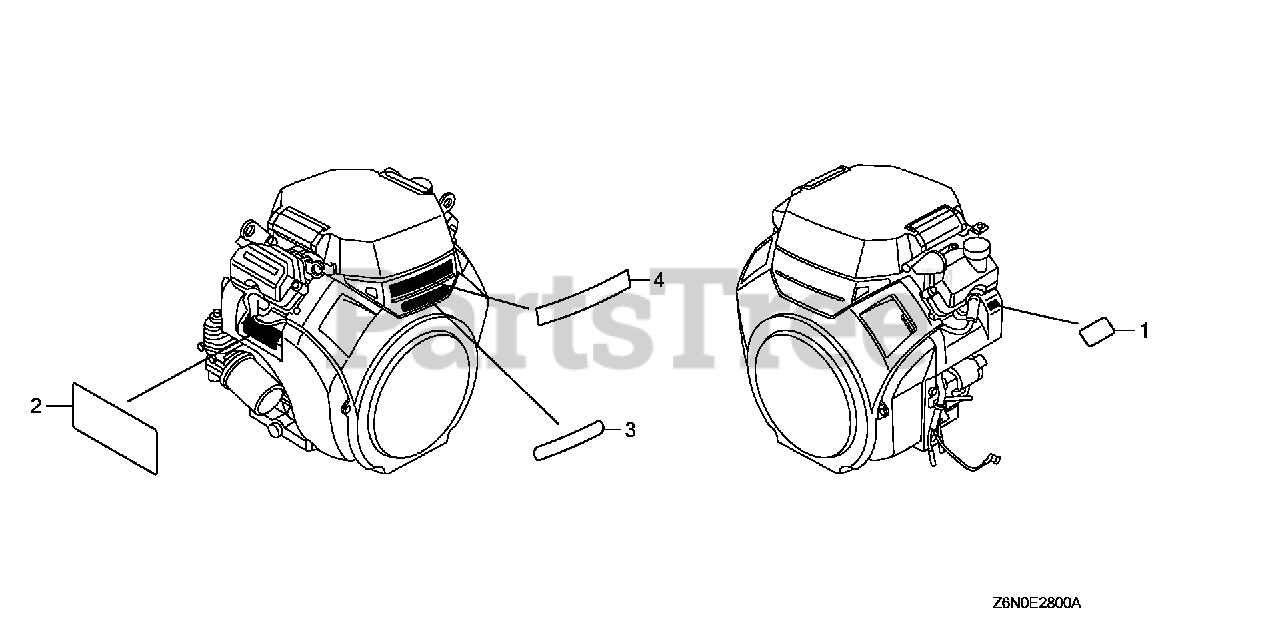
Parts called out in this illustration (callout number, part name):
1	LABEL, WARNING (NOT CERTIFIED FOR SALE)
2	MARK, OPERATOR CAUTION (CHINESE)(MADE IN JAPAN)
3	EMBLEM (GX690)
4	MARK, HONDA
